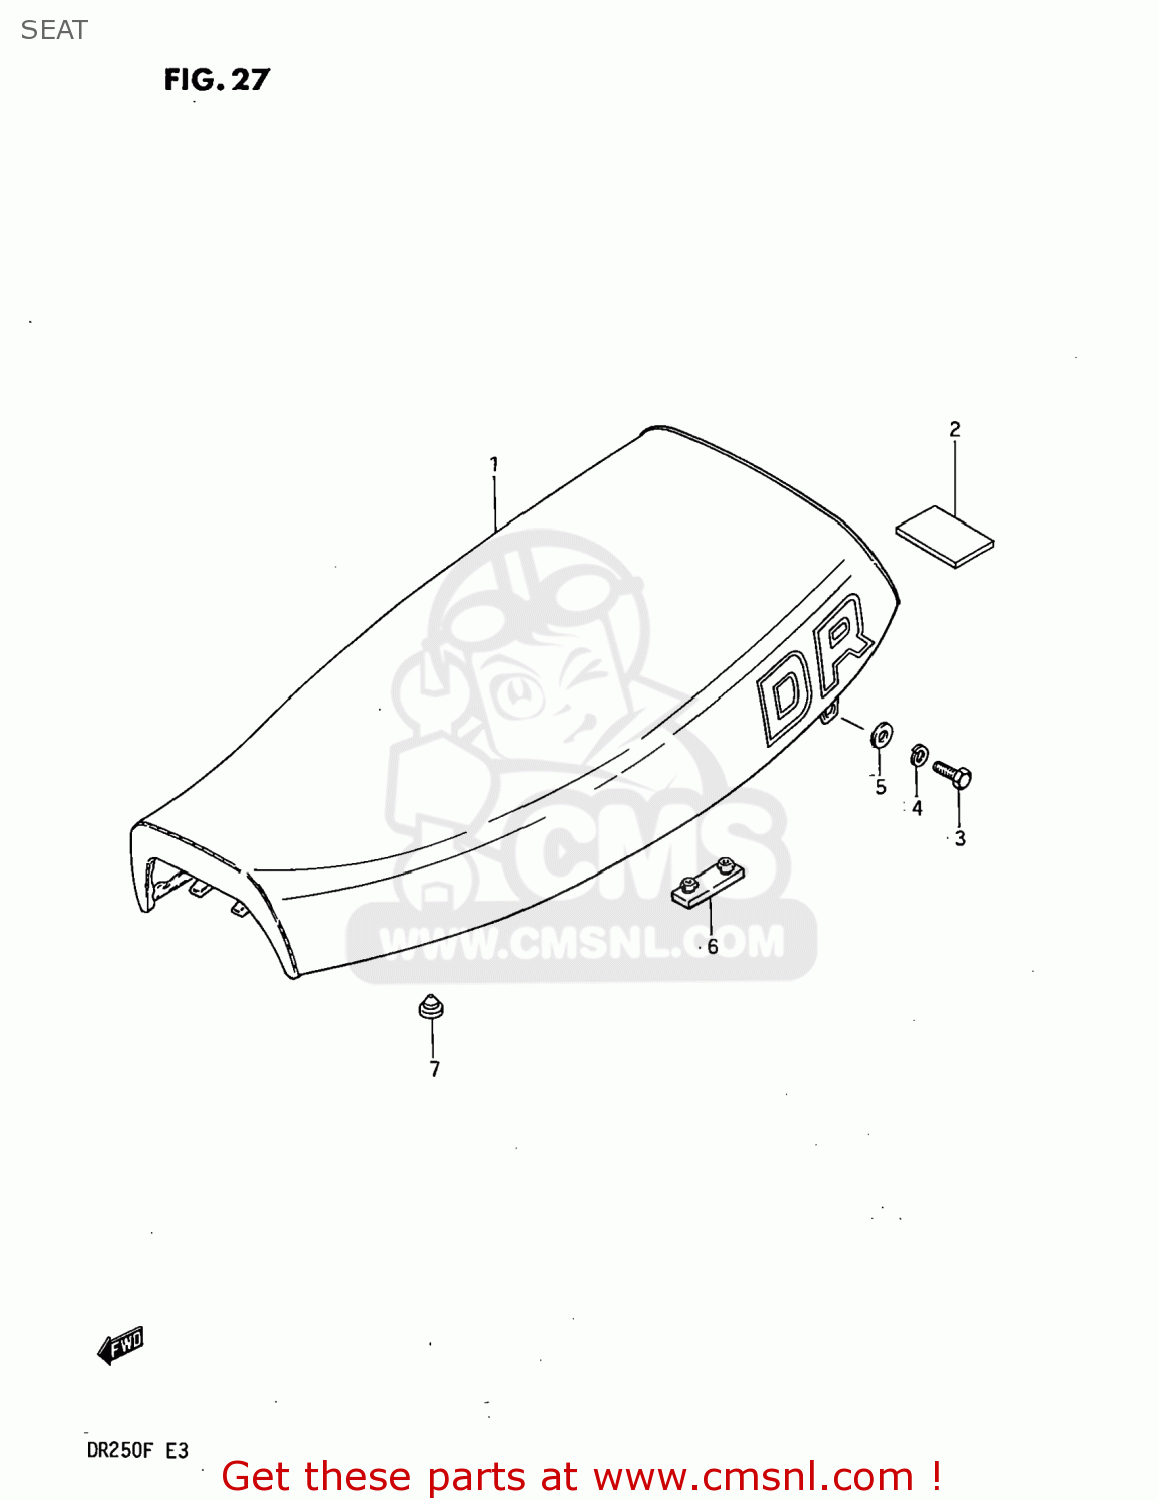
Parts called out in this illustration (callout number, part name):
1	SEAT ASSEMBLY
2	TAPE, SEAT UNDER
3	BOLT
4	WASHER,LOCK,8.
5	WASHER
6	CUSHION
7	CUSHION
